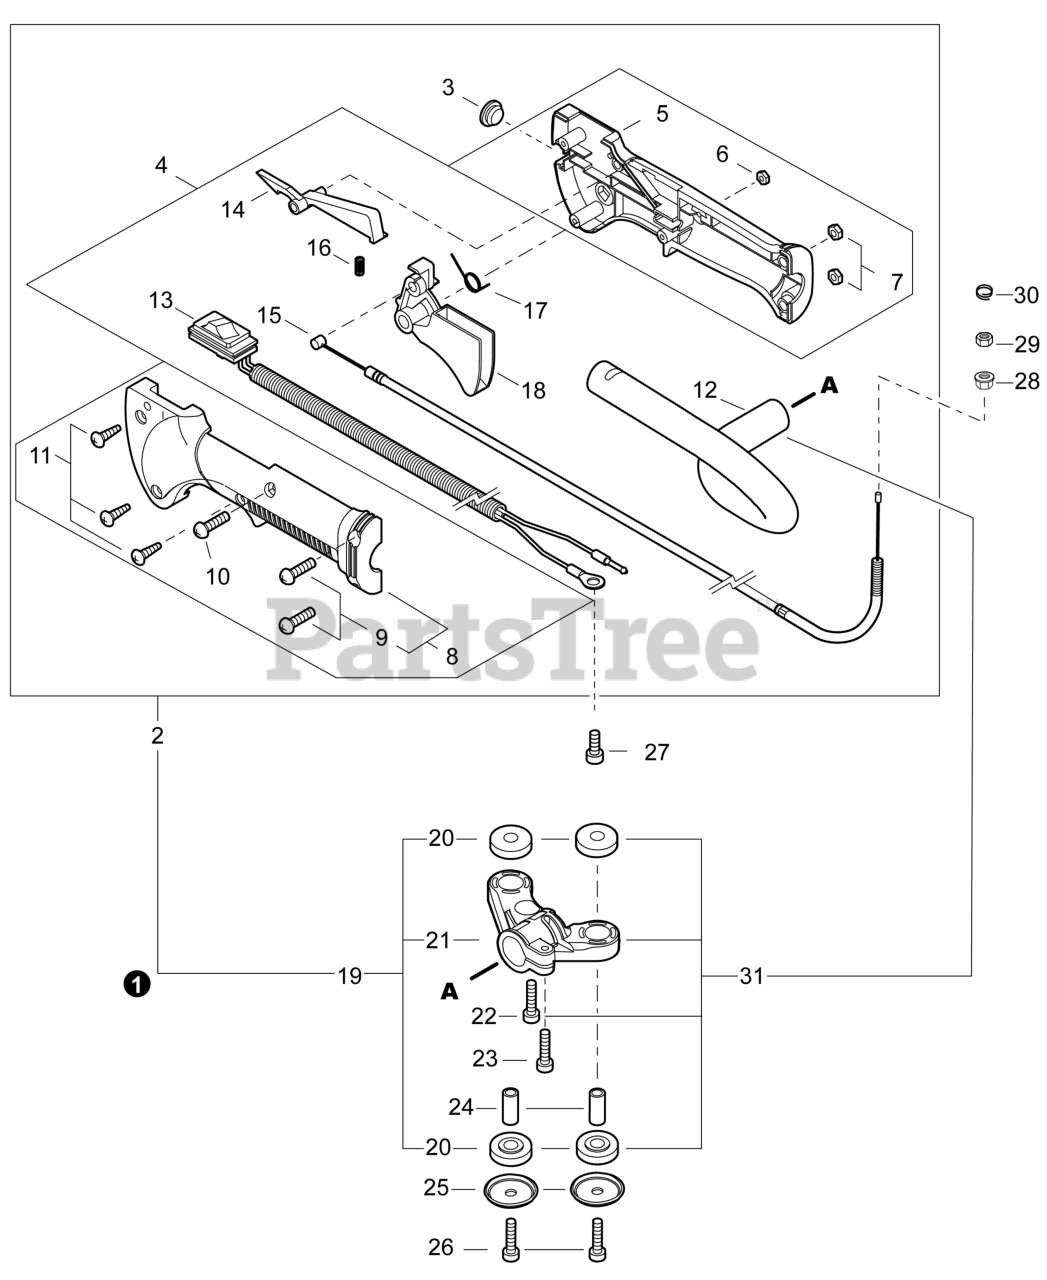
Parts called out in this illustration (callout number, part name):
1	HANDLE ASSY, REAR
2	HANDLE ASSY, REAR
3	PLUG, RUBBER
4	HANDLE KIT
5	CONTROL HANDLE - RIGHT
7	NUT, LOCK M5
8	CONTROL HANDLE KIT
9	SCREW M5×22
10	SCREW M4×23
11	SCREW, TAPPING 4×16
12	HANDLE, REAR
13	SWITCH ASSY, ON-OFF
14	LOCKOUT, THROTTLE
15	CABLE, THROTTLE
16	SPRING, COMPRESSION
17	SPRING, TORSION
18	TRIGGER, THROTTLE
19	SUPPORT ASSY, HANDLE
20	CUSHION
21	BRACKET, HANDLE
22	BOLT, TORX 5×20
23	BOLT, TORX 5×16
24	COLLAR 6
25	WASHER 6
26	BOLT, TORX 6
27	BOLT, TORX 4×10
28	NUT, FLANGE M6
31	HANDLE KIT, REAR
